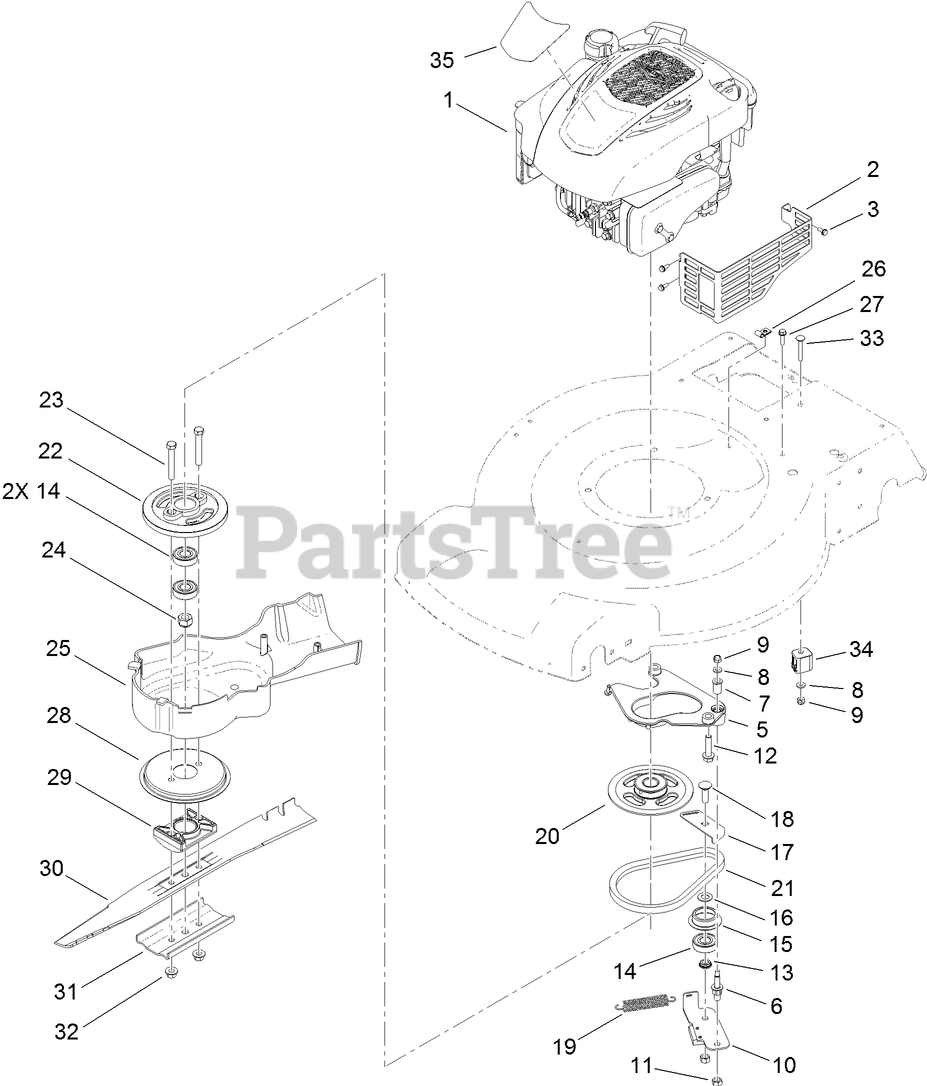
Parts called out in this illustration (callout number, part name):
2	SHIELD-MUFFLER
3	SCREW-TAPTITE
5	PLATE-ANCHOR
6	BOLT-SHOULDER
7	BUSHING
8	WASHER-FLAT
9	NUT-LOCK, NI
11	LOCKNUT
12	SCREW-HWH
13	SPACER-BEARING
15	RETAINER-BELT
16	SPACER
17	PLATE-GUIDE
18	BOLT-CARR
19	SPRING-TENSION, BRAKE
20	PULLEY
21	BELT
23	SCREW-HH
24	NUT-HEX
26	CLIP-CLOSED, INSULATED
27	SCREW-HWH
28	DISC
29	SUPPORT-BLADE
31	SUPPORT-BLADE
32	NUT-LOCK
33	SCREW-CARR
34	ANCHOR-CABLE
35	DECAL-SHROUD
